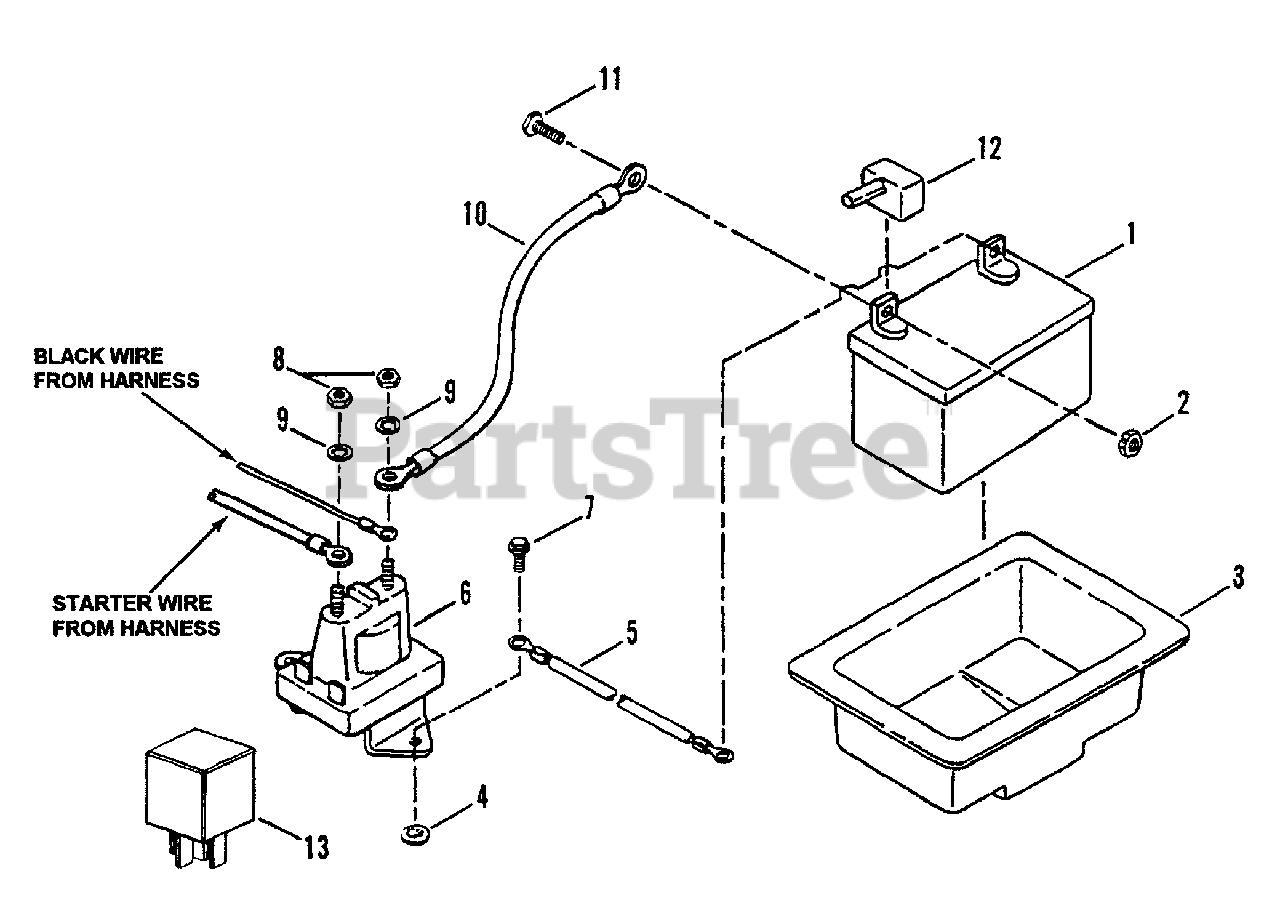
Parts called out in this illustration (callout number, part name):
1	KIT, Battery
2	NUT, 1/4-20 Hex Center Lock, Grade 5 or B
3	TRAY, Battery
4	RETAINER, Screw
5	CABLE, Ground (Black)
6	SOLENOID
7	SCREW, 1/4-20 x 1/2" Self-Tapping
8	NUT, 1/4-20 Hex Jam
9	WASHER, 1/4 Internal Tooth Lock
10	CABLE, Positive (Red)
11	SCREW, 1/4-20 x 5/8" Hex Head Cap, Grade 5
12	COVER, Positive Terminal
13	RELAY
